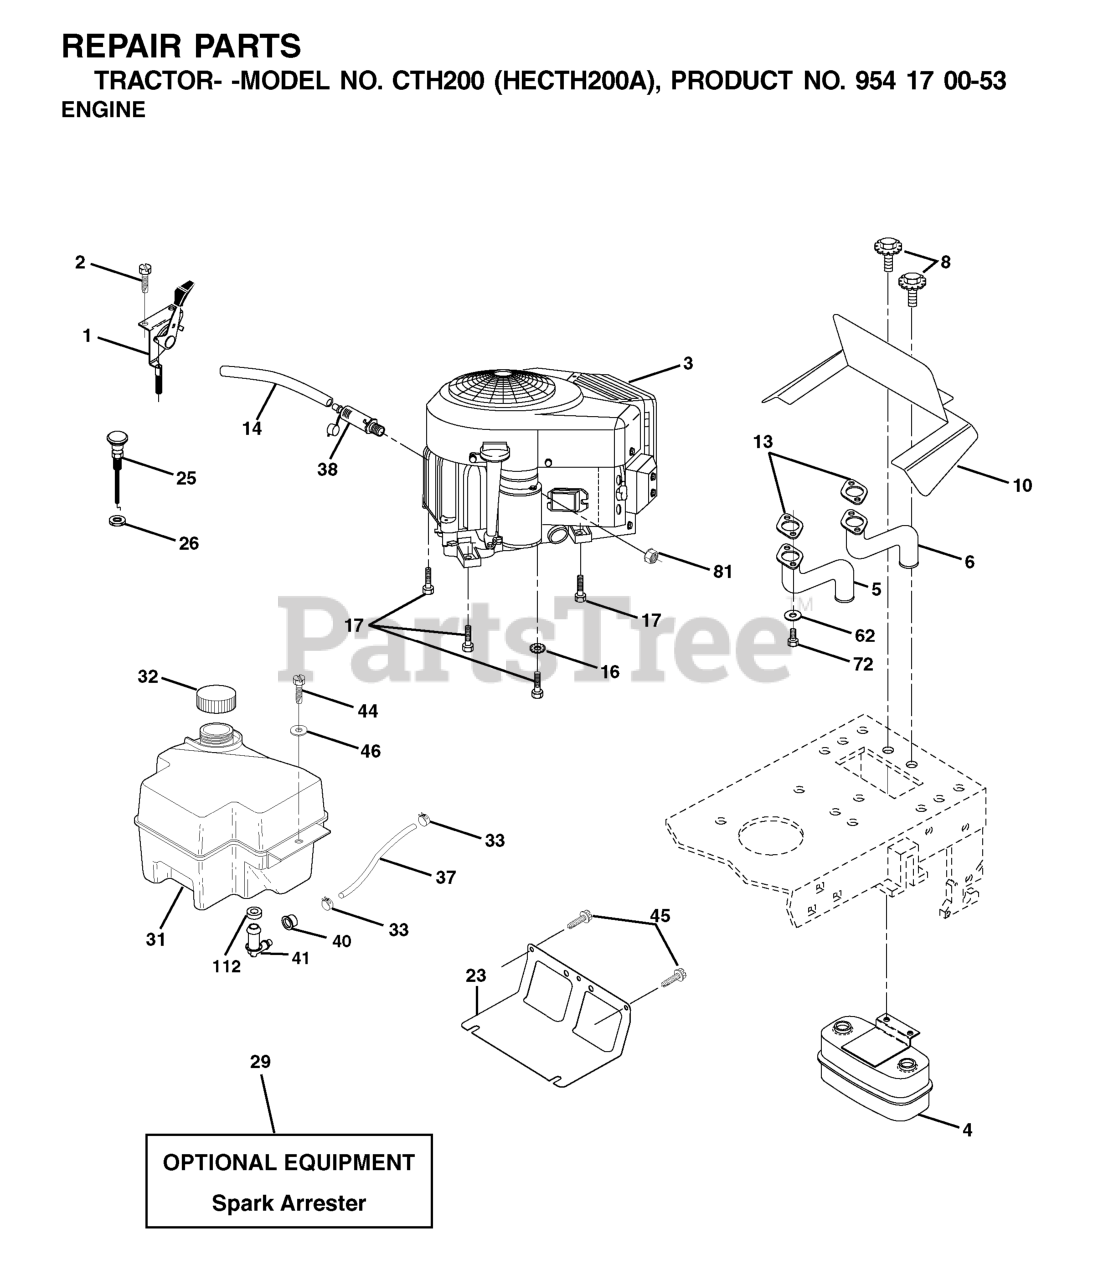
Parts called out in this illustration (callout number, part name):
1	CONTROL, THROTTLE
2	SCREW
4	MUFFLER.TWIN.CYL.LOW.TONE
5	RP.EXHAUST.TUBE.LH.BS/TWIN
6	EXHAUST.TUBE.RH.BS/TWIN
8	BOLT.5/16-18UNCX3/4 W/SEMS.BLK
10	SHIELD.BROWNING.B&S
13	GASKET.MUFFLER
14	TUBE, DRAIN OIL ASM.
16	LOCKWASHER
17	SCREW 3/8-16 X 1-1/2
23	SHIELD.BROWNING.DBR.GUARD
25	CONTROL, CHOKE
26	Nut Keps 3/8 - 24 UNF
29	KIT.SPARK ARRESTOR 794945 B&S
31	GAS TANK 2GAL
32	FUEL CAP
33	HOSE CLAMP
37	LINE.FUEL.20
38	PLUG, OIL DRAIN EASY
40	BUSHING.SNAP.NYL.BLK.
41	STEM FUEL TANK
44	SCREW HEXWSHR 1/4-20X3/4
45	SCREW, 3/8-16X3/4
62	WASHER.LOCK.HVY.HLCL.SPR.5/16
72	SCREW
81	NUT
112	BUSHING OUTLET T
